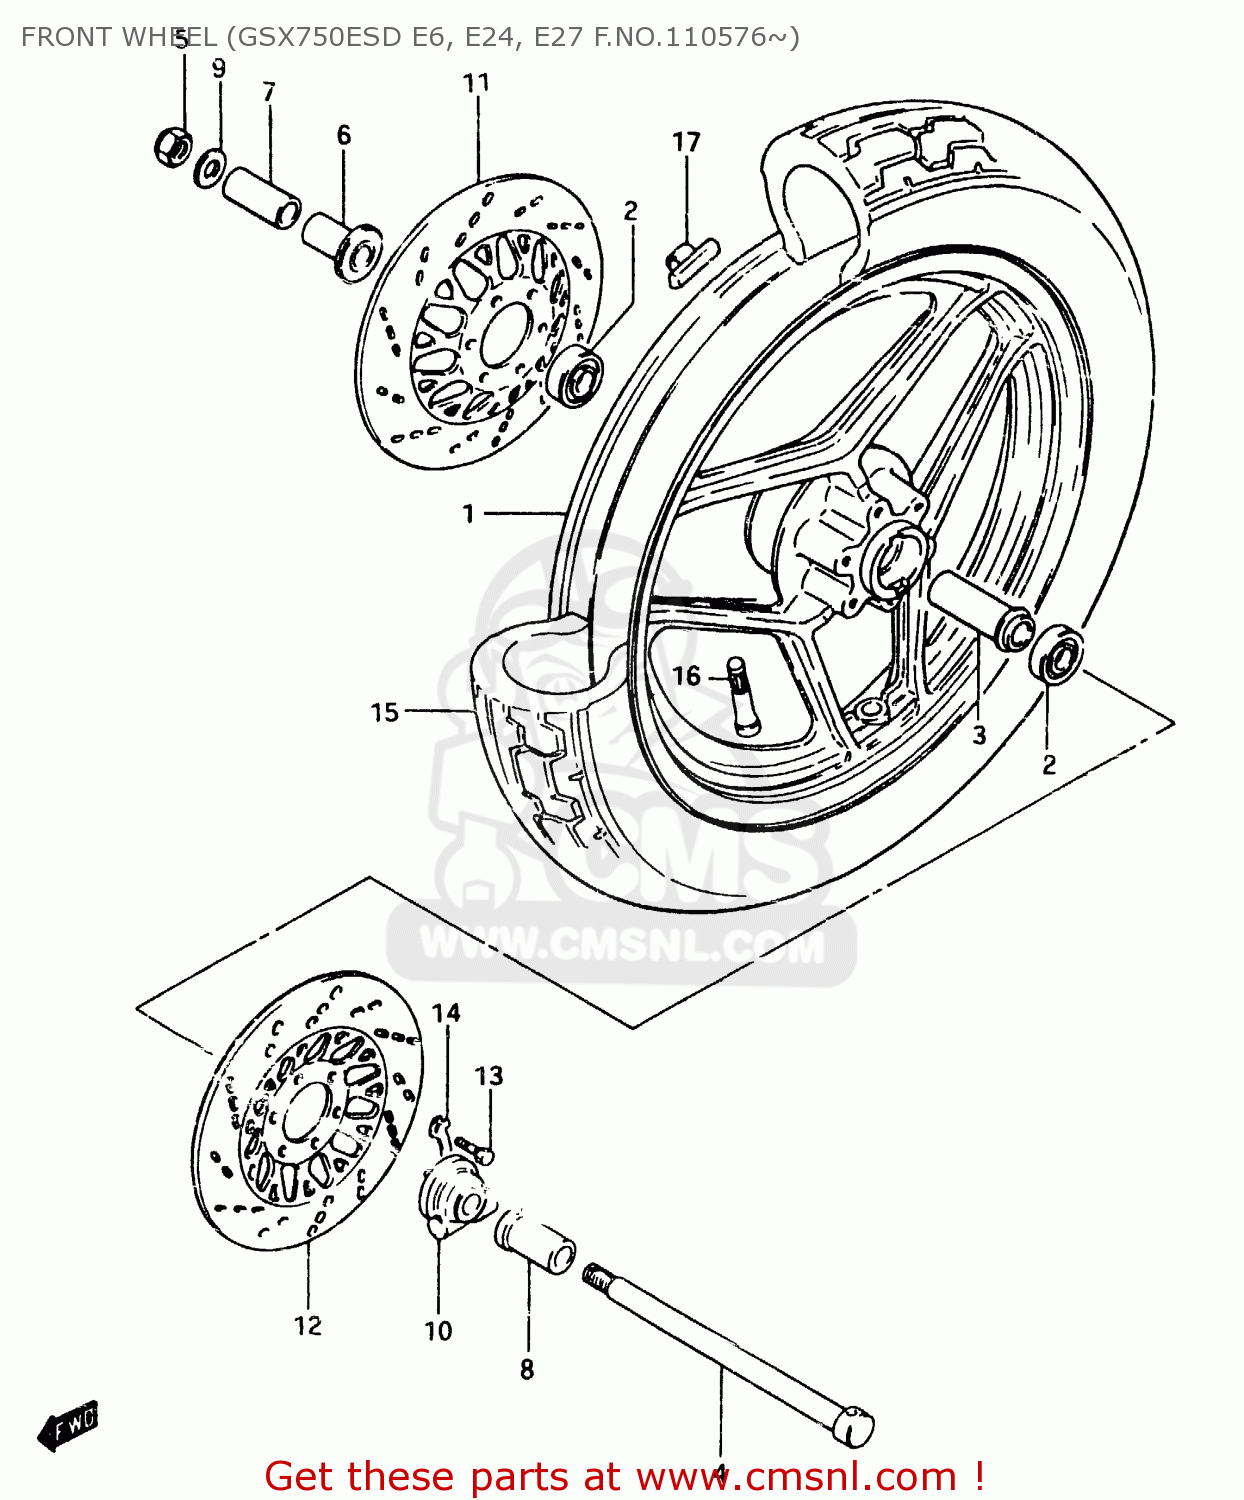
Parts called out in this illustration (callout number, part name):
1	WHEEL, FRONT (MT2.50X16)
2	BEARING
3	SPACER,FRONT HUB BEARING
4	AXLE,FR
5	NUT
6	SPACER,FR AXLE,R
7	SPACER, AXLE RH
8	SPACER,FR AXLE,L
9	WASHER
10	BOX ASSEMBLY,SPEEDOMETER GEAR
11	DISC,BRAKE,RIGHT
12	DISC,BRAKE,LEFT
13	BOLT(8X25)
14	WASHER
15	TIRE, TUBELESS (120/80V16)
16	VALVE,TIRE
17	BALANCER,WHEEL
